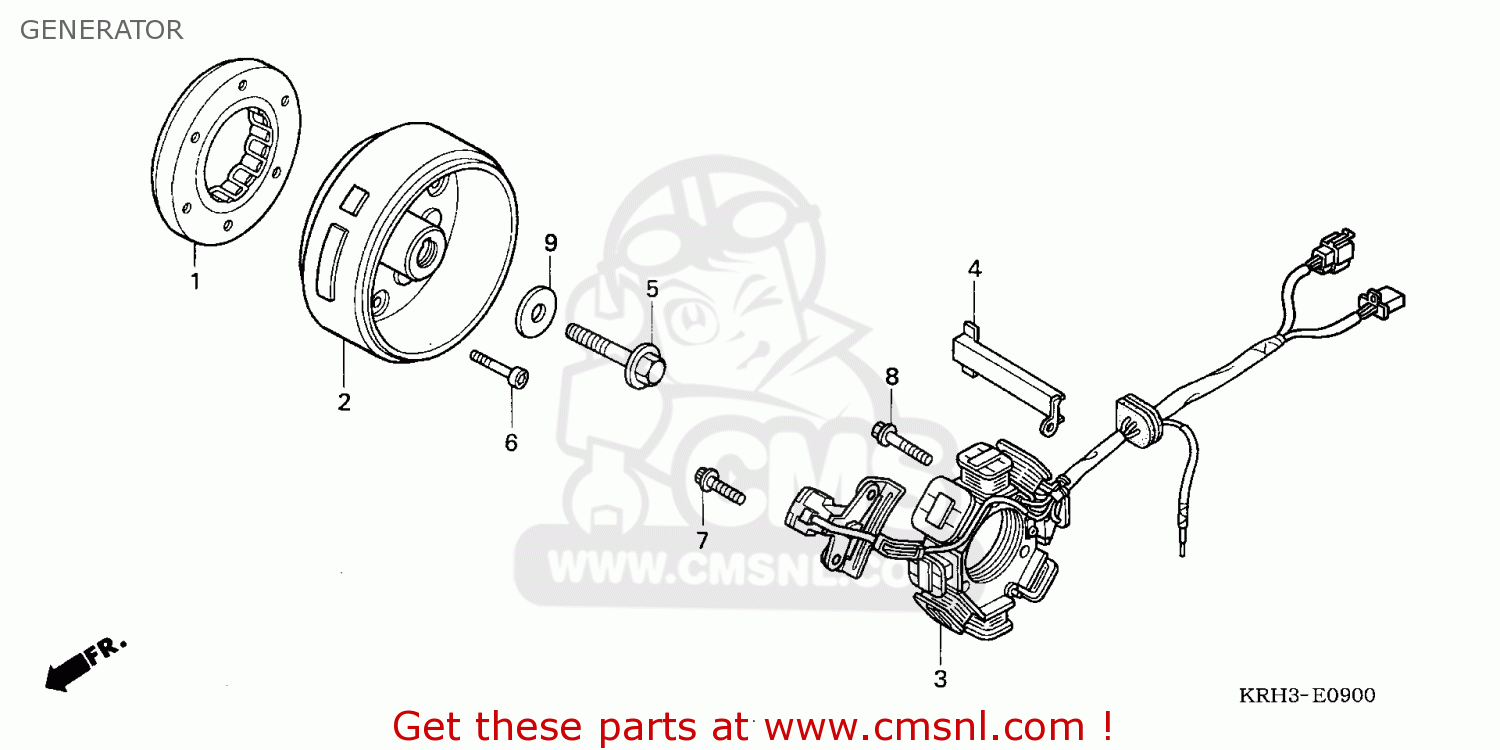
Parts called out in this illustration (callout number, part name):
1	OUTER COMP,STARTI
2	FLYWHEEL COMP.
3	STATOR COMP.
4	GUIDE,ACG.CORD
5	BOLT,ROTOR SETTIN
6	BOLT,SOCKET 6MM
7	BOLT,FLANGE SOCKE
8	BOLT,STPR.TENS.
9	WASHER,10X24
